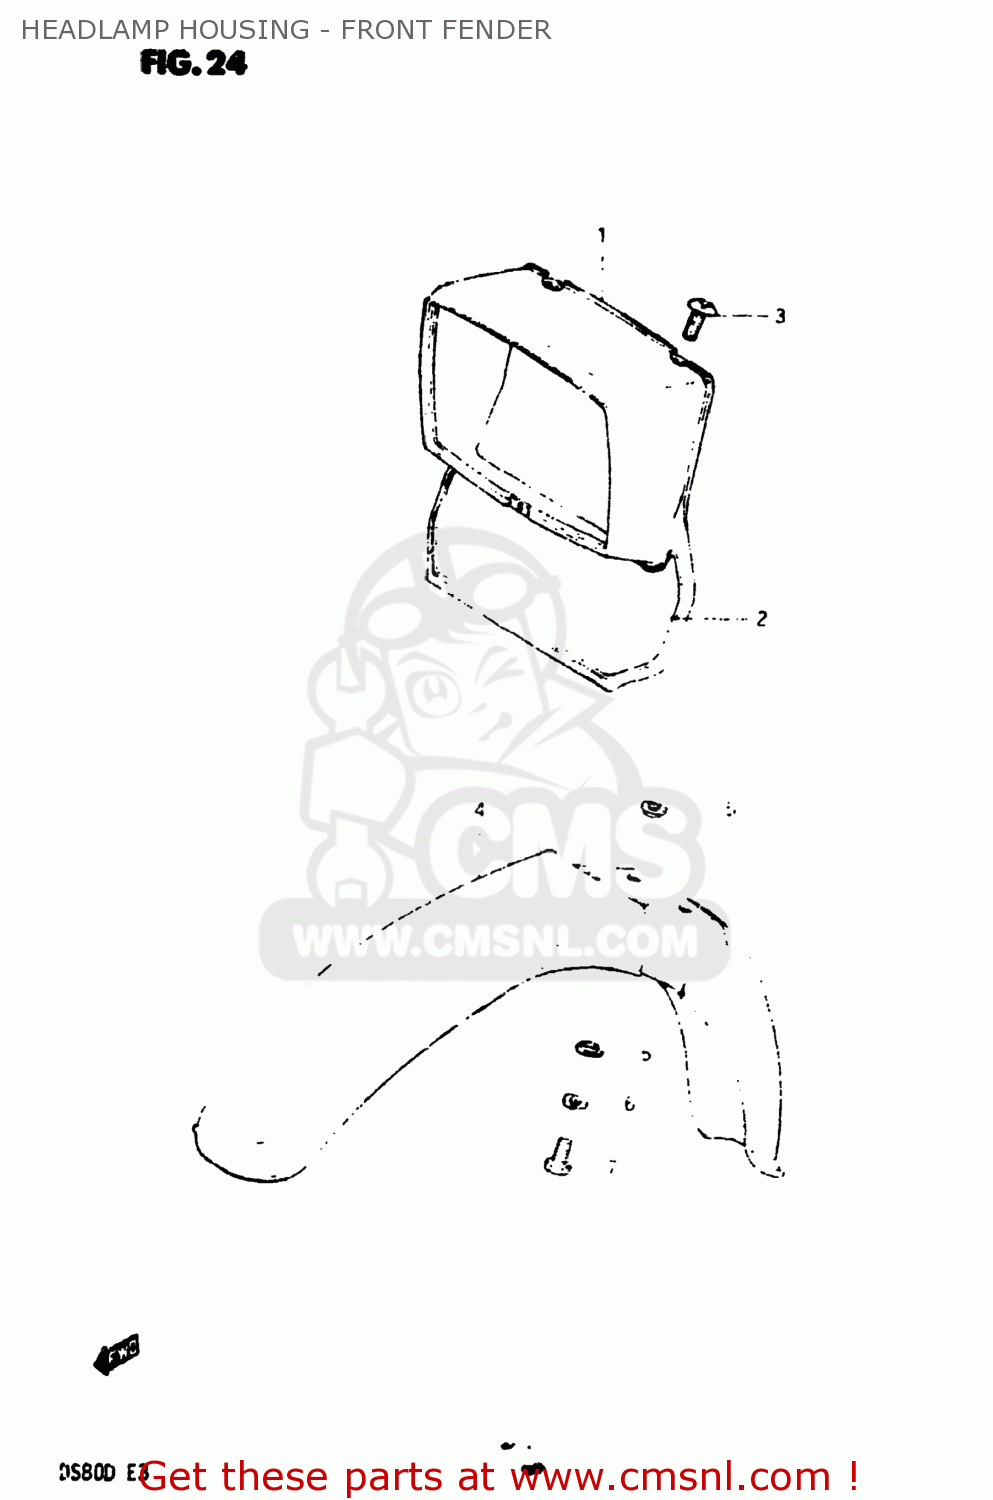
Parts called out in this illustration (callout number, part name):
1	HOUSING,HEADLAMP
2	EMBLEM,FRONT NUMBER PLATE
3	SCREW
4	FENDER,FR
5	SPACER
6	LOCK WASHER
7	BOLT, UPPER
